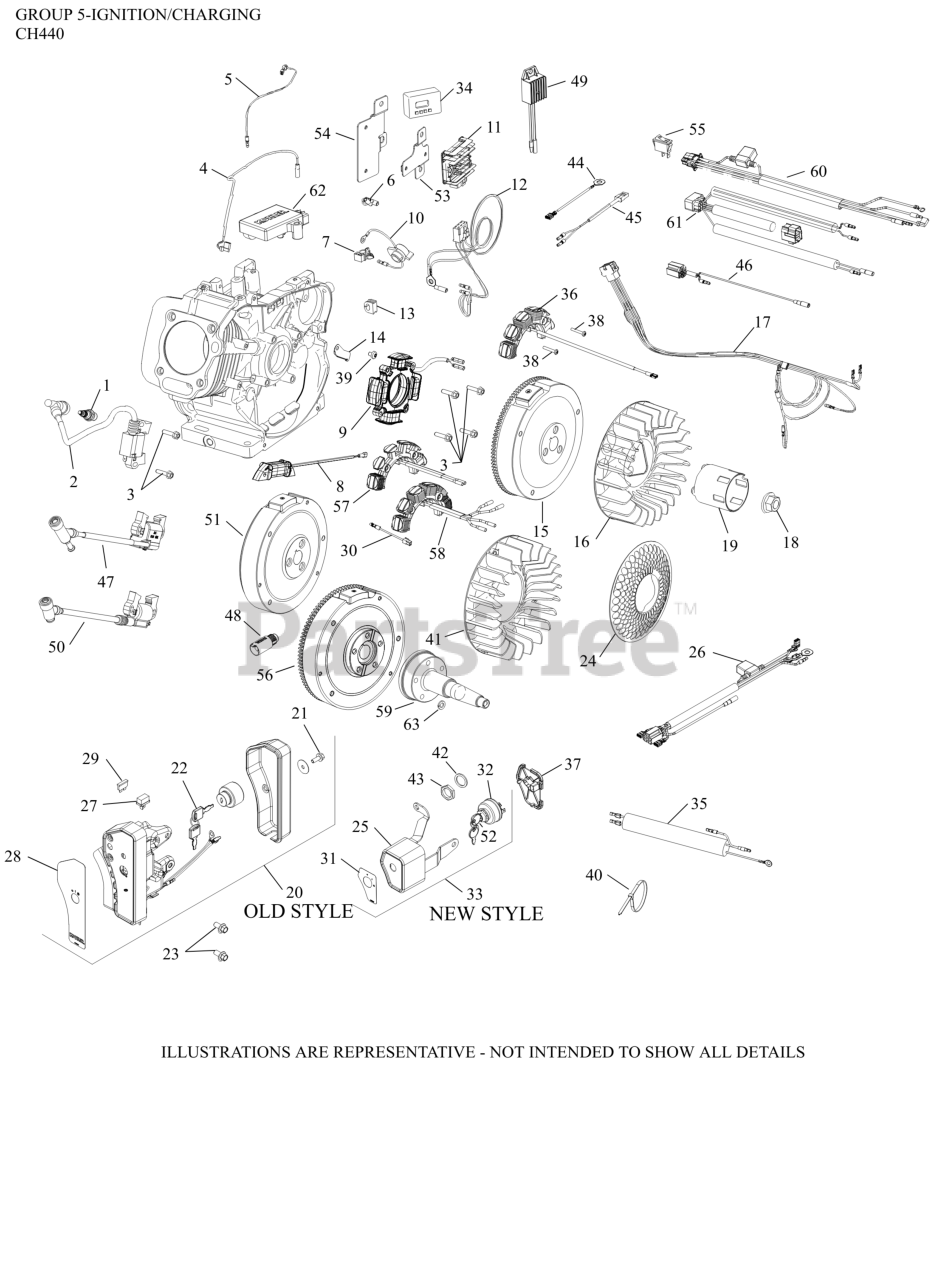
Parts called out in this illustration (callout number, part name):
1	SPARK PLUG
2	MODULE, IGNITION
3	SCREW, M6 X 25-(#25086436S)
4	LEAD, GROUND TO KILL
15	FLYWHEEL ASSY ELECTRIC START (CH440)
16	FAN, FLYWHEEL
18	NUT, FLYWHEEL
19	CUP, STARTER DRIVE
21	SCREW, HEX FLANGE (M6)-USE 25 086 433-S
22	KEY, SET OF 2
25	KEYBOX HOUSING ASSEMBLY
26	HARNESS, WIRING ASSEMBLY (3 AMP)
31	LABEL, KEY BOX
32	SWITCH, KEY ASSEMBLY
33	KIT, KEY BOX ASSEMBLY
37	COVER, KEY BOX
52	KIT, KEY PLASTIC HANDLE (2 PC)
